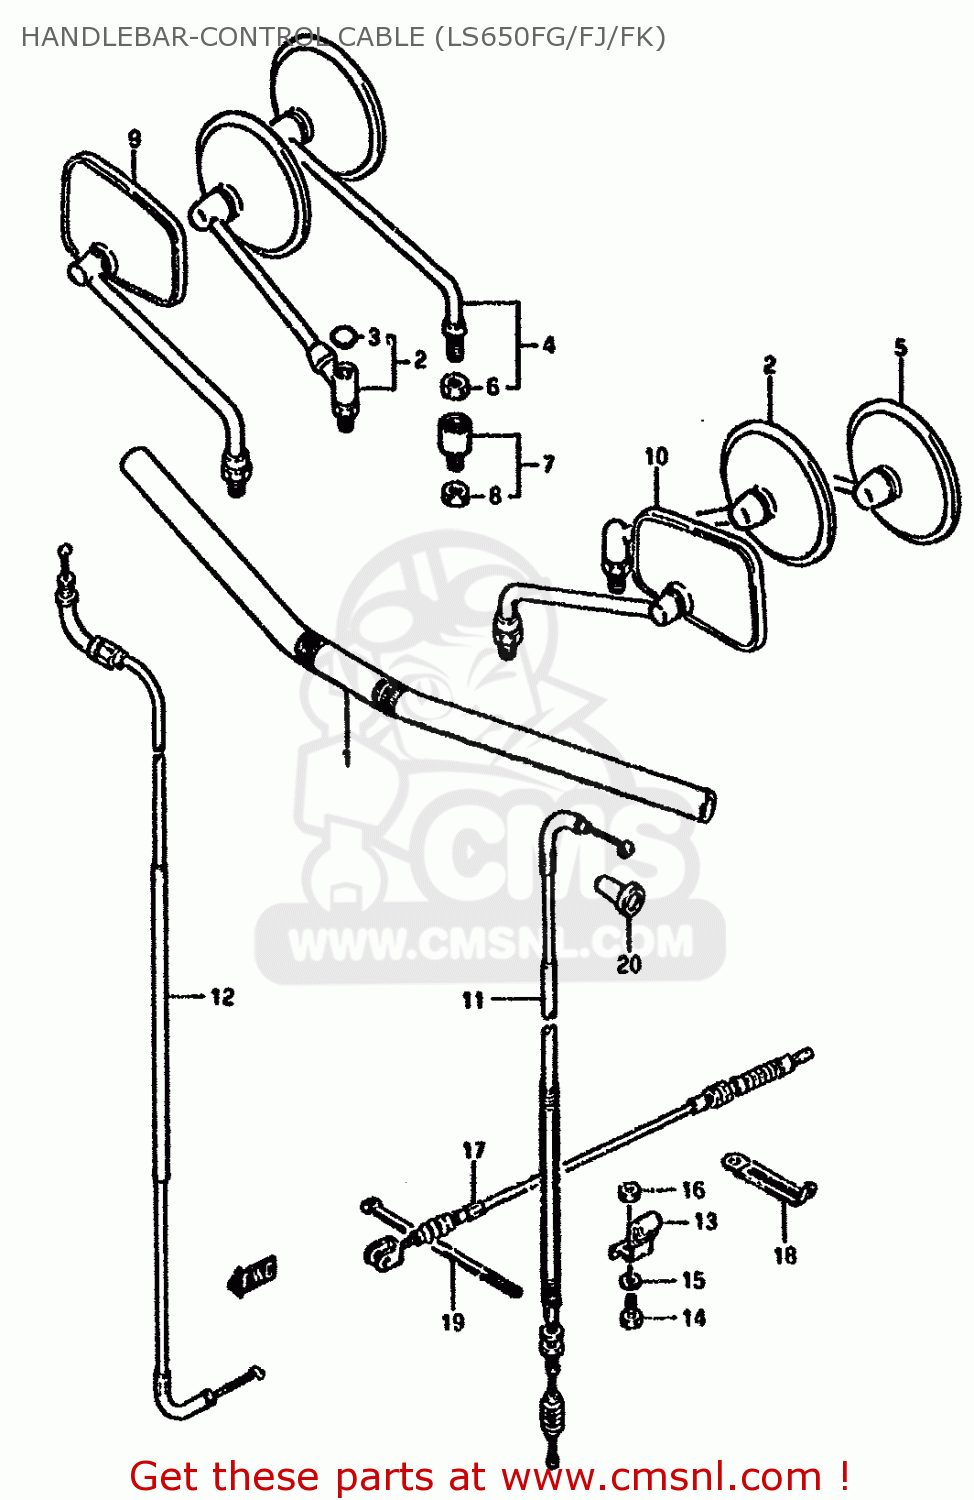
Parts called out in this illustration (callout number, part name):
1	HANDLEBAR
2	MIRROR ASSY,R.
3	CAP
4	MIRROR ASSY RH
5	MIRROR ASSY
6	NUT
7	CUSHION,REAR VIEW MIRROR
8	NUT
9	MIRROR ASSY,RR VIEW,R
10	MIRROR ASSY,RR VIEW,L
11	CABLE ASSY,CLUTCH
12	CABLE ASSY,THROTTLE
13	GUIDE,CABLE
14	BOLT 6X16
15	WASHER,LOCK
16	NUT
17	CABLE COMP,STOP LAMP SWITCH
18	CLAMP
19	CLAMP
20	BOOT,CLUTCH CABLE
